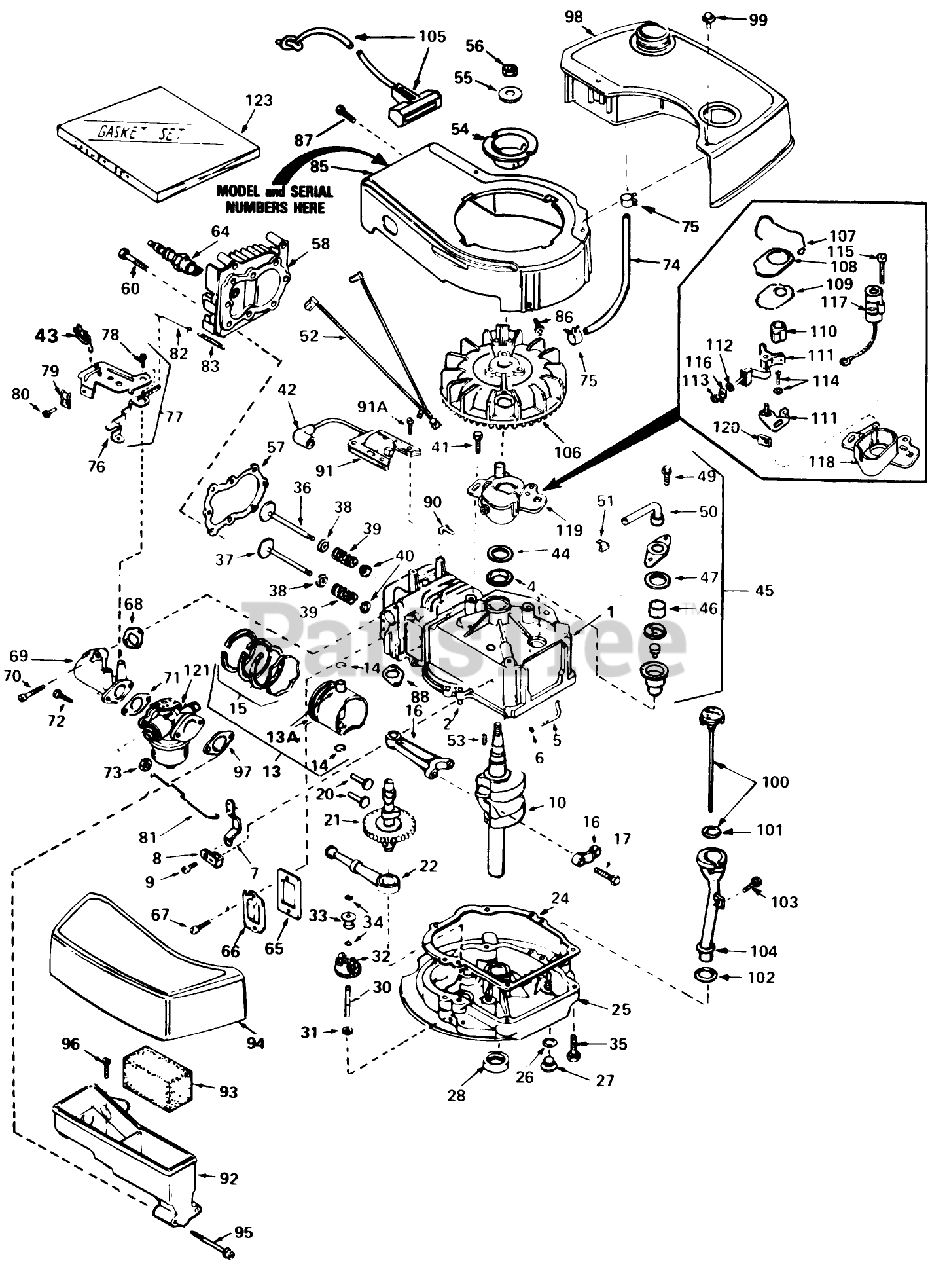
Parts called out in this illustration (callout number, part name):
1	Cyiinder Assy. (Incl. Ref. #2, 4 105)
2	Pin-Dowel
4	Seal-Oil
5	Rod, Governor (Incl. No. 36)
6	Washer-Flat
7	Governor Lever
8	Clamp-Lever, Governor
9	Screw
10	Crankshaft
13	Piston, Pin Ring Assy. (Std.)(Incl. Ref. #13A, 14 15)
13	Piston,Pin Ring Assy. (.010 over-size)(Incl. Ref. #13A, 14 15)
13	Piston, Pin Ring Assy. (Incl. Nos. 13A, 14 15)(.020 oversize)
13A	Piston Pin Assy. (Incl . Ref. . #14) (Std.)
13A	Piston Pin Assy. (Incl. Ref. #14) (.010 Oversize)
13A	Piston Pin Assy. (.020 oversize) (Incl. Ref. #14)
14	Ring-Retaining, Piston Pin
15	Ring Set Piston (Std.)
15	Ring Set Piston (.010 Oversize)
15	Ring Set Piston (.020 Oversize)
16	Rod Assy., Connecting (Incl. Ref. #17)
17	Bolt-Rod, Connecting
20	Lifter-Valve
21	Camshaft(Mech.Comp. Release)
22	Oil Pump ASM
24	Gasket, Mounting
25	Flange Assy., Mounting (Incl. Ref. #26thru 30)
26	Gasket-Oil Drain
27	Plug Oil Drain
28	Seal Oil
30	Shaft-Governor
31	Washer-Flat
32	Governor Gear ASM
33	Spool-Governor
34	Ring-Retaining
35	Screw (1/4-20 x 1-1/4)
36	Valve, Intake (Incl. Ref. #38, 39 40) (Std.)
36	Valve, Exhaust (1/32" Oversize) (Incl. Nos. 8, 9 10)
37	Valve, Exhaust (Standard) (Incl. Nos. 8, 9 10)
37	Valve, Exhaust (1/32" Oversize) (Incl. Nos. 8, 9 10)
38	Cap-Upper Valve Spring
39	Spring-Valve
40	Cap-Valve, Spring
41	Screw
42	Cover-Spark Plug
43	Terminal
44	Gasket Stator
45	Breather Assy. (Incl. Ref. #46 thru 51)
46	Element-Breather
47	Gasket-Breather
49	Screw (10-24 x 9/16)
50	Tube, Breaker
51	Clip, Breather
52	Wire Ground
53	682488 LB GRASS HI-
54	Hub-Starter
55	Washer-Belleville
56	Nut-Flywheel
57	63573 GIL 42 SNWTHW
58	Head-Cylinder
60	Screw
64	Plug, Spark (J17LM or equiv.)
64	Plug, Spark (Champion RCJ-8)
65	Gasket-Breather
66	Cover-Valve
67	Screw
68	Gasket-Intake
69	Pipe, Intake (Incl. No. 68)
70	Screw (1/4-20 x 1)
71	Gasket-Carburetor
73	Nut and Lock Washer (1/4-28)
74	Line-Fuel
75	Clamp-Line, Fuel
76	Lever Control
77	Control Assy., Speed (Incl. Nos, 76, 78 89)
78	Screw, Hex Washer Hd Shoulder Self-Tap
79	Conduit
80	Screw (10-32 x 3/8)
81	Link-Throttle
82	Link Governor Spring
83	Spring Governor
85	Housing Blower
86	Screw
87	Screw (10-24 x 9/16)
88	Gasket Exhaust
90	Clip-Wire
91	Lamination Coil Assy. (Incl. No. 42)
91A	Screw
92	Body Air Cleaner
93	Filer, Air
94	Cove, Air Cleaner
95	Screw Fil Hd.
96	Screw, Hex Hd.
97	Gasket-Air Cleaner
98	Tank, Fuel
99	Screw (10-32 x 35/64)
100	Dipstick, Oil (Incl. Ref. #101)(Twist Lock)
101	O-Ring
102	Gasket
103	Screw (10-32 x 1/2)
104	Tube-Oil Fill
105	Rope Assy., Starter
106	FIywheel
107	Spring Breaker Box
108	Cover-Dust
109	Gasket-Dust Cover
110	Cam-Breaker
111	Breaker Assy.
112	Washer
113	DECAL
114	Breaker Screw
115	Condenser Screw
116	Terminal, Ground
117	Condenser
118	Stator Plate
119	Stator Plate Assy. (incl. Nos. 107, 111 thru 118 120)
120	Felt,Cam Wiper
121	Carburetor (Incl. Ref. #71 )
123	Gasket Set
